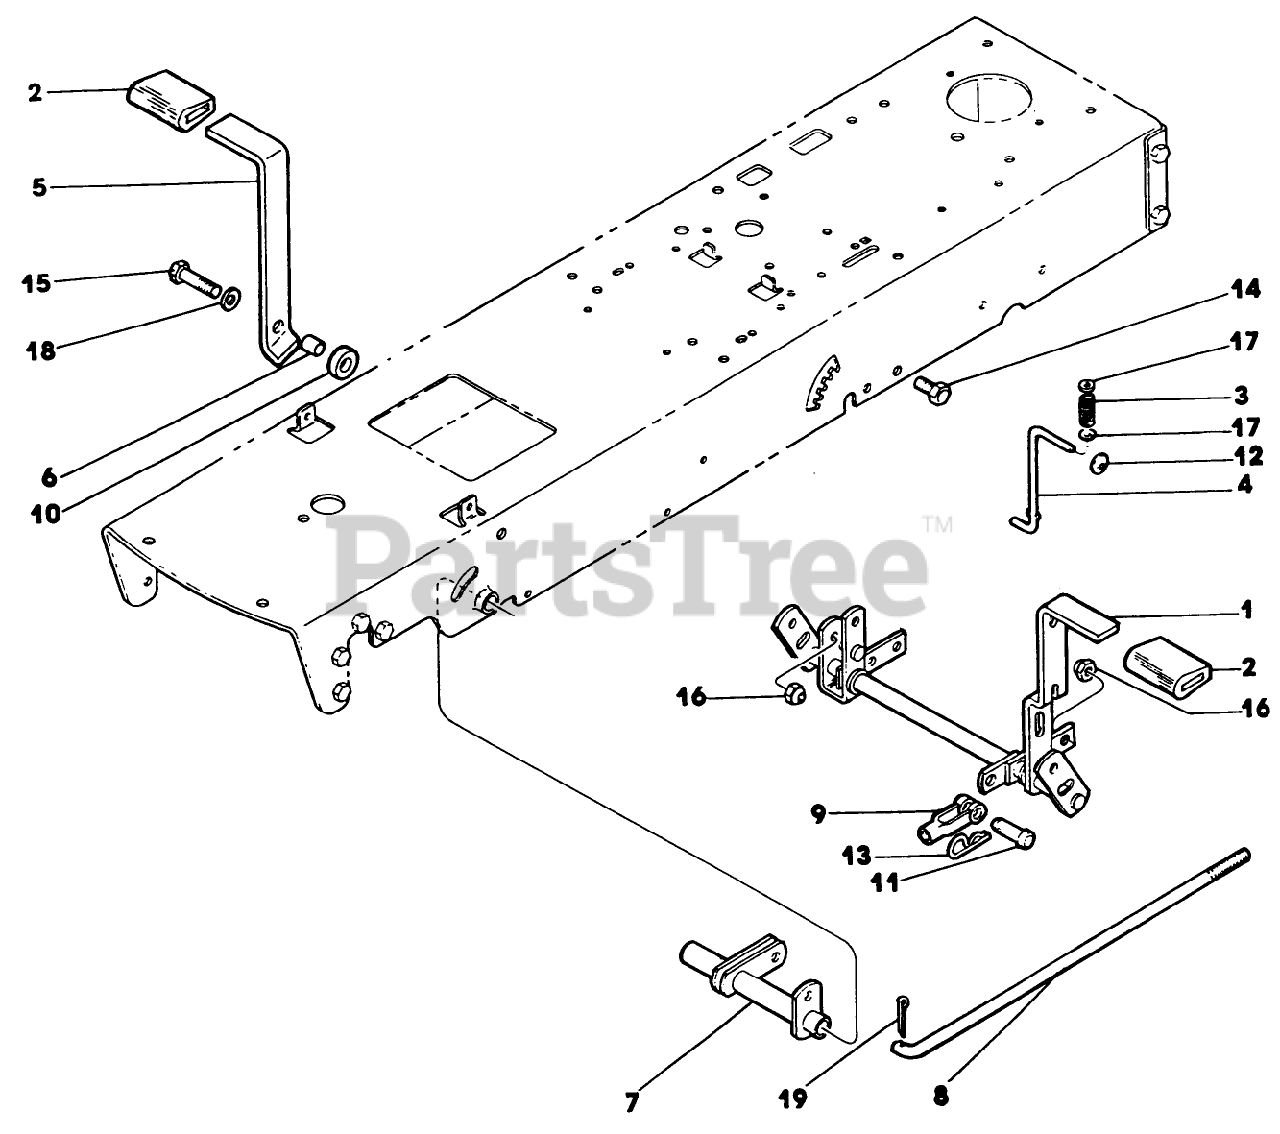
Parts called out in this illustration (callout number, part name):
2	GRIP
7	CROSS SHAFT WA*B
11	PIN CLEVIS
13	PIN - SPRING CLIP
16	NUT-LOCKING
18	WASHER
